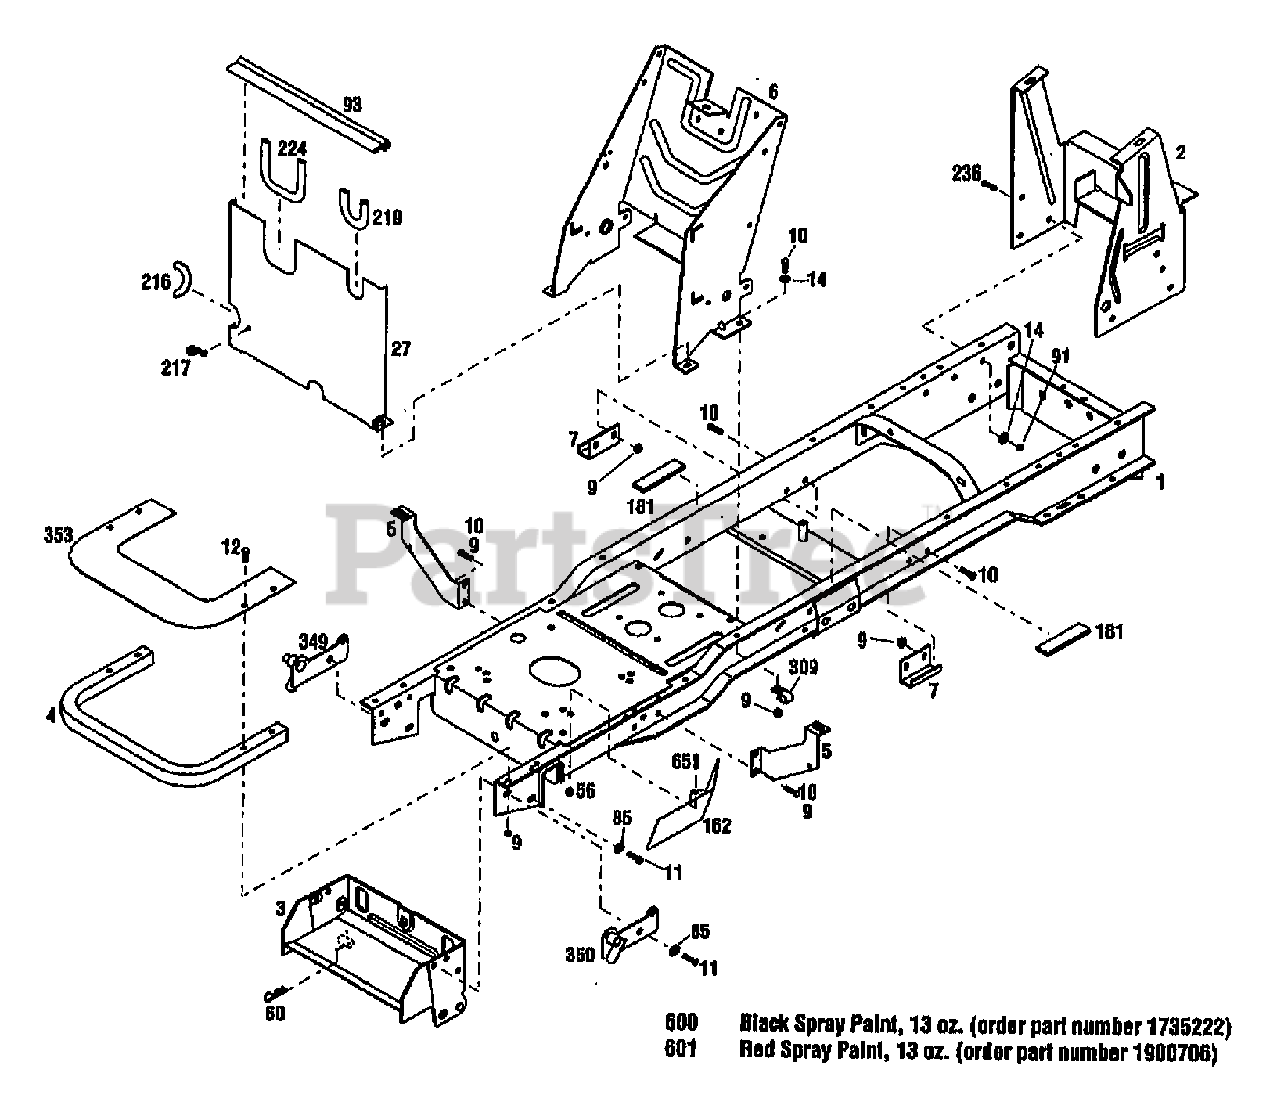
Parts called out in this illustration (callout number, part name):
1	ASSM-FRAME LTX
2	SUPPORT-REAR TANK
3	ASSM-BRKT ATTACHMENT
4	BUMPER-FRONT
5	SUPPORT-FENDER
6	SUPPORT-CONSOLE
9	NUT-HFLK 5/16-18 ZP
10	SCR-HHC 5/16-18X.75 GR 5 ZP
11	SCR-HH 3/8-16X1.0 G5 ZP
12	SCR-HH 5/16-18X1.75
14	WASHER-FLAT 5/16 SAE
27	SHIELD-HEAT
60	PIN-HITCH .125X2.56 ZP
85	WASHER-FLAT 3/8 SAE
91	NUT-TOP/LK 5/16-18 ZP
93	GASKET-HEAT SHIELD {13037}
162	SHIELD-HEAT UPPER
216	TRIM {13037}
217	HANGER-CABLE {13037}
219	TRIM {13037}
224	TRIM-HEAT SHIELD {13037}
236	SCR-HFLK 5/16-18X.75 ZP
309	CLIP-J
349	PLATE-PIVOT RH
350	PLATE-PIVOT LH
353	SHIELD-HEAT {13036/037}
600	PAINT-BLACK SPRAY
601	PAINT-RED SPRAYCAN POWDER
